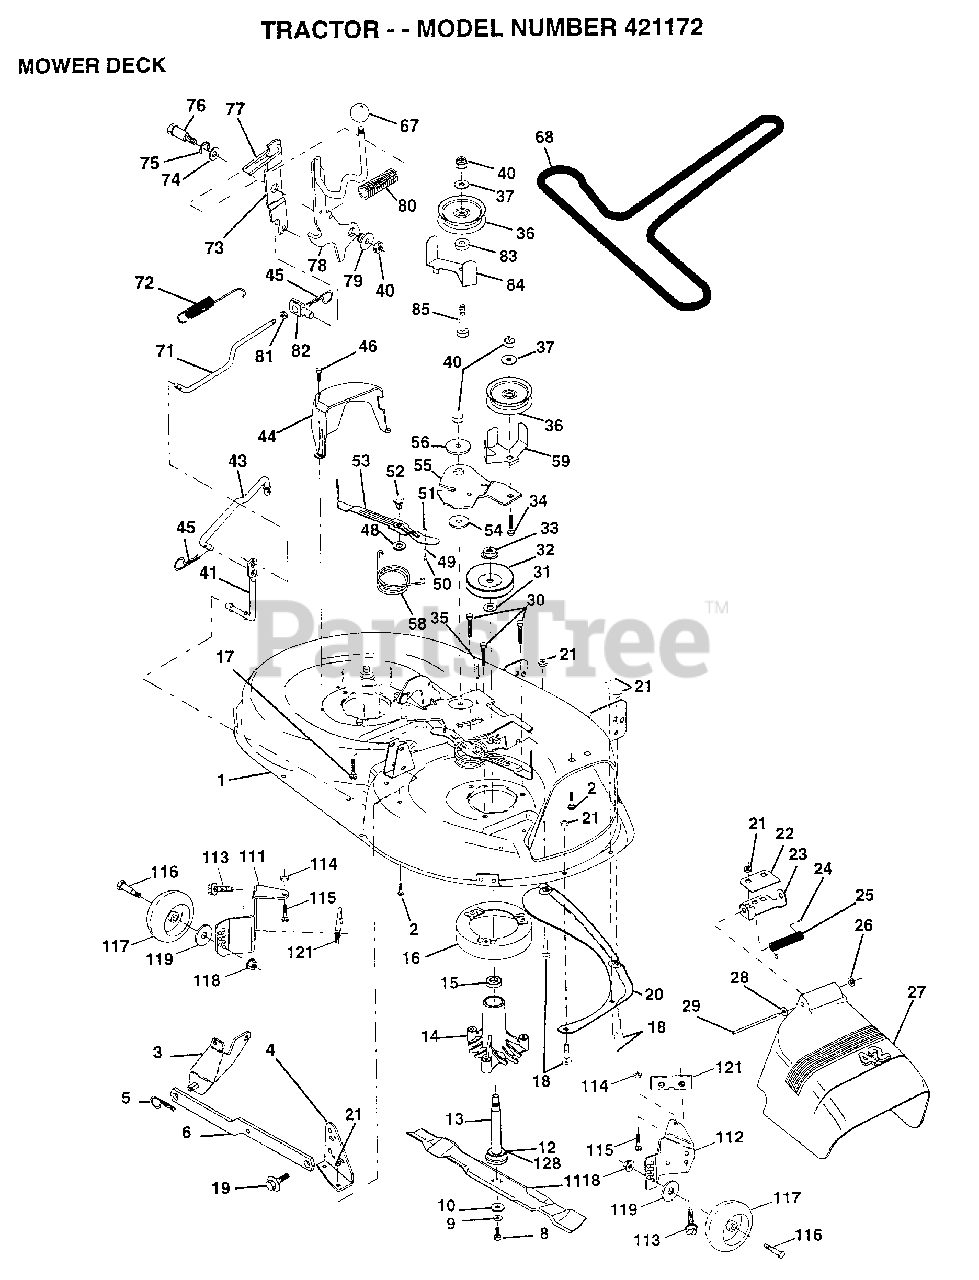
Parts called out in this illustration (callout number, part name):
1	DECK.WELD.42.
2	BOLT
3	BRKT ASM SWAY BAR
4	BRKT DECK SW BAR
8	BLADE BOLT
10	WASHER.HARD.BLADE
11	"BLADE.42"" HIPERF"
12	BEARING.BALL
14	HSG ASM MANDREL
15	BEARING
16	STRIPPER RND MWR
17	BOLT RDHD 3/8-16
18	BOLT
19	BOLT SHD 5/16-18
22	STIFFENER BRKT
23	DEFLECTOR BRKT
24	CAP-SLEEVE LT
25	SPRING TORSION
26	NUT PUSH M
27	DEFLECTOR.SHIELD
28	WASHER
29	HINGE ROD
31	WASHER
32	PULLEY.MANDREL.42
34	BOLT
35	XMAS TREE FASTNER
36	FLAT IDLER PULLEY
37	WASHER
41	PIVOT ROD
43	ROD CLUTCH W/NIBS
44	GUARD MAND LH BLK
45	RETAINER M
46	SCREW.1/4-20X5/8
48	HARD SMALL WASHER
50	SHOULDER BOLT
51	LOCKNUT
52	BOLT.SHLD.5/16-18
53	BRAKE PAD ARM ASM
54	HARDENED WASHER
56	SPACER RETAINER
58	SPRING TORSN BRAK
59	GUARD IDLER TUV
67	KNOB T (1/2-HOLE)
68	BELT.V.T-PATH
71	ROD CLUTCH 38/42
72	RETURN SPRING
73	CLUTCH ARM SECOND
74	WASHER
75	RING
76	SHOULDER BOLT
77	SPRING KEEPER
78	LEVER ASM CLT PRM
79	BUSHING
80	SPRING.CLUTCH.MWR
81	NUT
82	TRUNION ADJ
83	WASHER
85	BOLT RDHD 3/8-16
113	SCREW
116	BOLT.SHOULDER
117	WHEEL.GUAGE.MED.
118	LOCKNUT
119	WASHER
121	BRACKET.EXTRD.GWL
128	WASHER.FELT.
